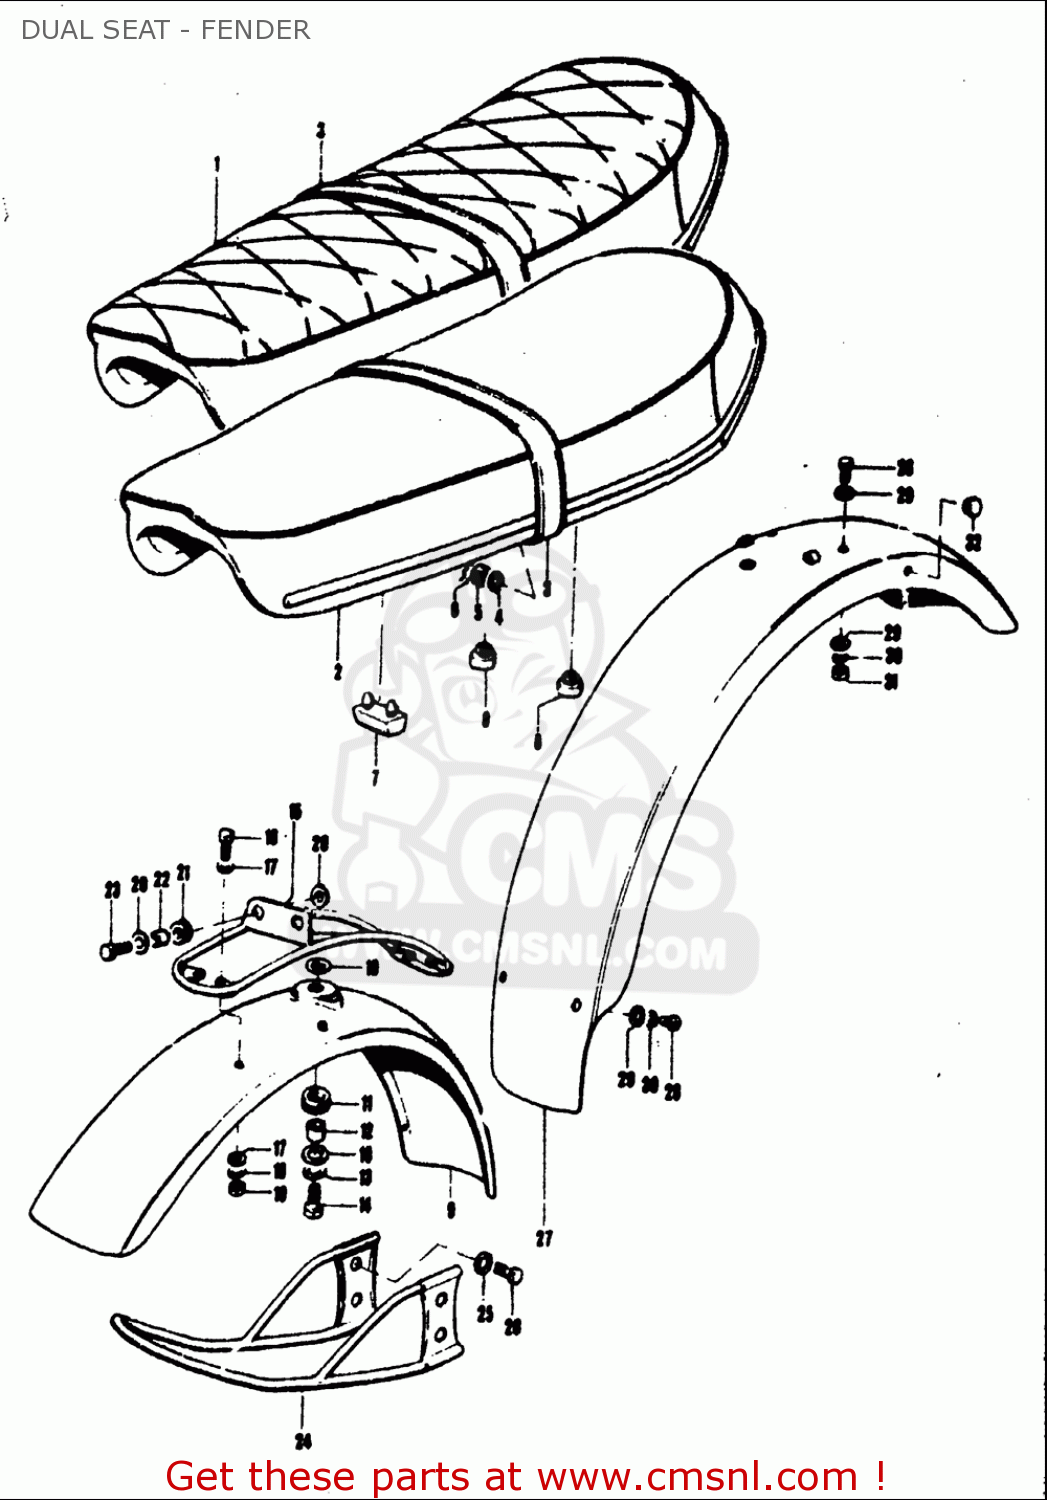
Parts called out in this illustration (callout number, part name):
4	WASHER
5	NUT
6	CLIP
7	CUSHION
8	CUSHION
10	WASHER(8.5X26X1.6)
11	CUSHION
12	SPACER(8.2X10X8)
13	WASHER,LOCK
14	BOLT
17	WASHER
18	WASHER,LOCK
19	NUT
20	WASHER(6.5X20X1.2)
21	CUSHION
22	SPACER,6.5X9X7
25	WASHER,LOCK
28	BOLT(6X14)
29	WASHER
30	WASHER,LOCK
31	NUT
